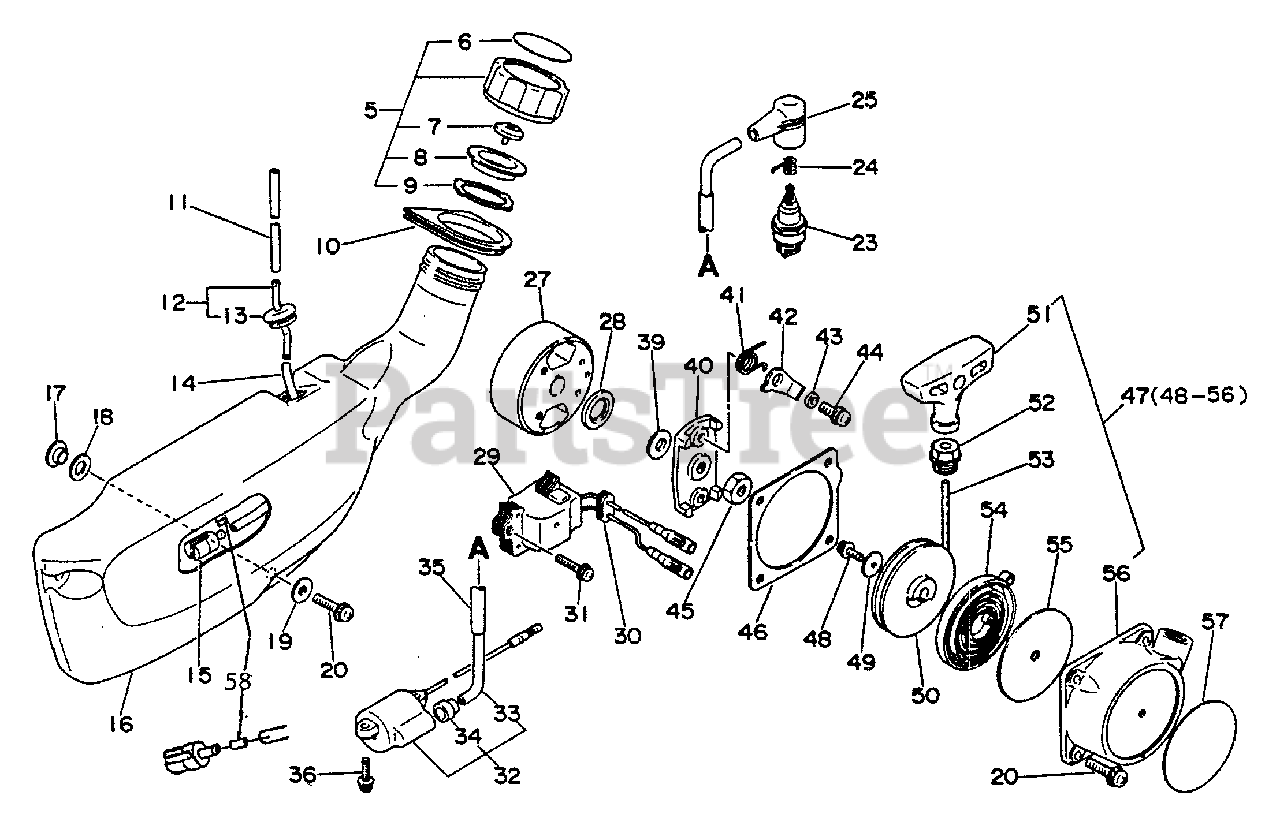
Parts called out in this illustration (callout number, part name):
5	CAP ASSY
6	LABEL - FUEL MIX
8	HOLDER, VENT
9	GASKET, CAP
10	BUSHING
11	PIPE - FUEL
12	CONNECTOR
14	PIPE - FUEL
15	FILTER, FUEL
16	TANK, FUEL
18	WASHER - RUBBER
20	SCREW - 5X20
23	SPARK PLUG -- CJ-7Y
24	TERMINAL, SPARK PLUG CAP
25	CAP, SPARK PLUG
27	FLYWHEEL
29	COIL, IGNITION
31	SCREW - 4X20
32	COIL, IGNITION
33	CORD, HIGH TENSION
34	CORD, HIGH TENSION
36	SCREW - 4X14
39	WASHER - 8
40	CATCHER, PAWL
41	SPRING, RETURN
42	PAWL, STARTER
44	SCREW - 5X10
45	NUT - 8 -- LEFT HAND
46	GASKET, STARTER
47	STARTER ASSY
48	SCREW - 4X10
50	REEL, ROPE
51	GRIP, STARTER
52	GUIDE, ROPE
53	ROPE, STARTER - 3X850
54	SPRING, REWIND
55	PLATE, STARTER
56	CASE, STARTER
57	LABEL - ECHO
